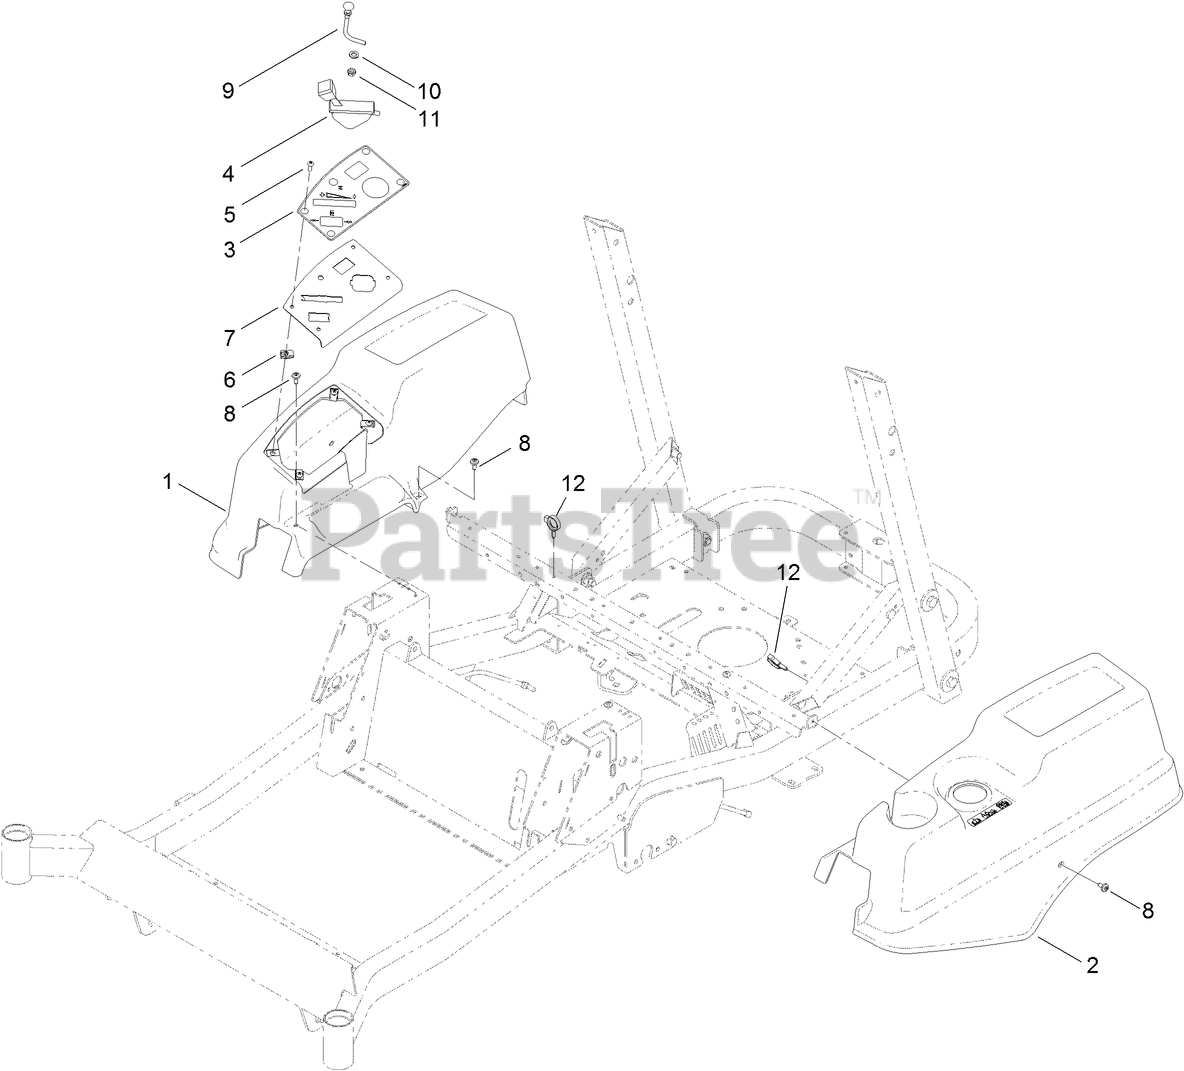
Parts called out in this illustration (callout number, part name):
1	POD-RH
2	POD-LH
3	DECAL-PANEL, CONTROL
4	CABLE-THROTTLE
5	SCREW-PRH
7	PANEL-CONTROL
8	SCREW-SHOULDER
9	CABLE-CHOKE
10	WASHER-LOCK
11	NUT-HJ
12	CLAMP-HOSE
